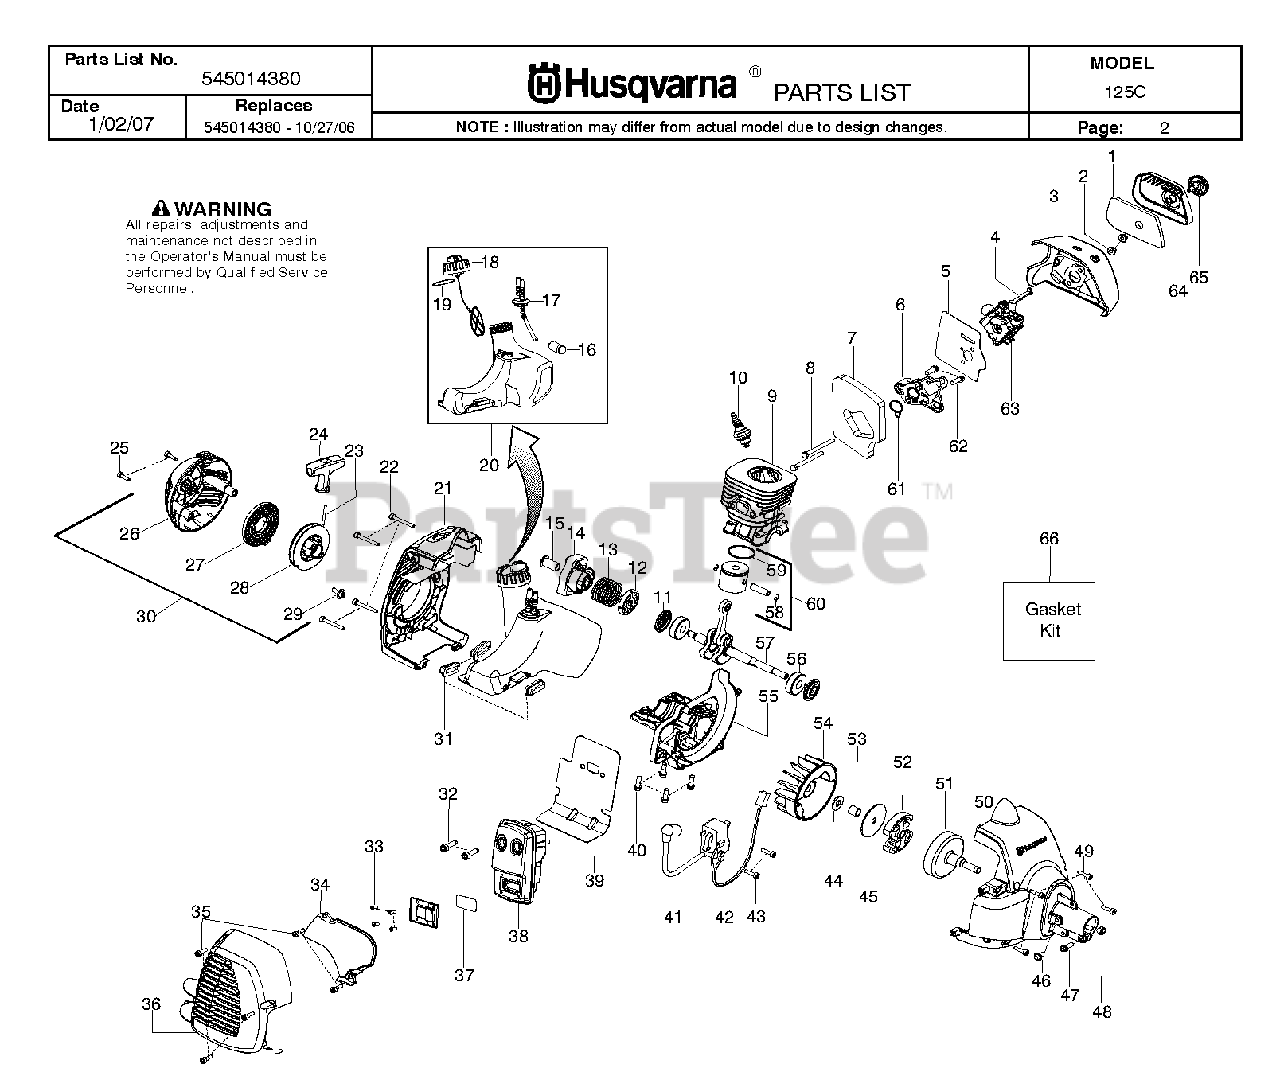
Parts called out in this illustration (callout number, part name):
2	Nut-Carb. Screw
3	Air Box
4	Lever - Choke
5	Kit-Carb. Gasket
6	Adaptor-Carb.
7	Kit-Gasket
9	Cylinder
10	Plug-Spark
11	Kit-Crankshaft seal
12	Washer-Starter
13	Spring-Starter Cup
14	Assy-Starter Cup
15	Coupling-Starter
16	Assy-Fuel Filter
17	Kit-Fuel Line
18	Assy-Cap w/ret.
19	O-ring - Fuel Cap
20	Assy-Fuel Tank
21	Shroud-Rear
24	Handle-Starter
26	Starter Hsg. w/eyelet
27	Kit-Starter Spring
28	Kit-Starter Pulley
30	Assy-Starter Hsg.
31	Isolator-Tank
32	Bolt-Muffler
34	Shield-Heat
36	Guard-Muffler
37	Kit-Spark Arrestor
38	Assy-Muffler
39	Gasket-Paper Metal
42	Assy-Leadwire
45	Washer-Clutch
50	Assy-Fan Housing
51	Assy-Clutch Drum
52	Kit-Clutch Assy.
55	Crankcase-Cast
57	Kit-Crankshaft
58	Retainer-Piston Pin
59	Ring-Piston
60	Kit-Piston
61	Kit-Gasket
63	Kit-Carb.
64	Cover-Air Box
66	Kit-Gasket
